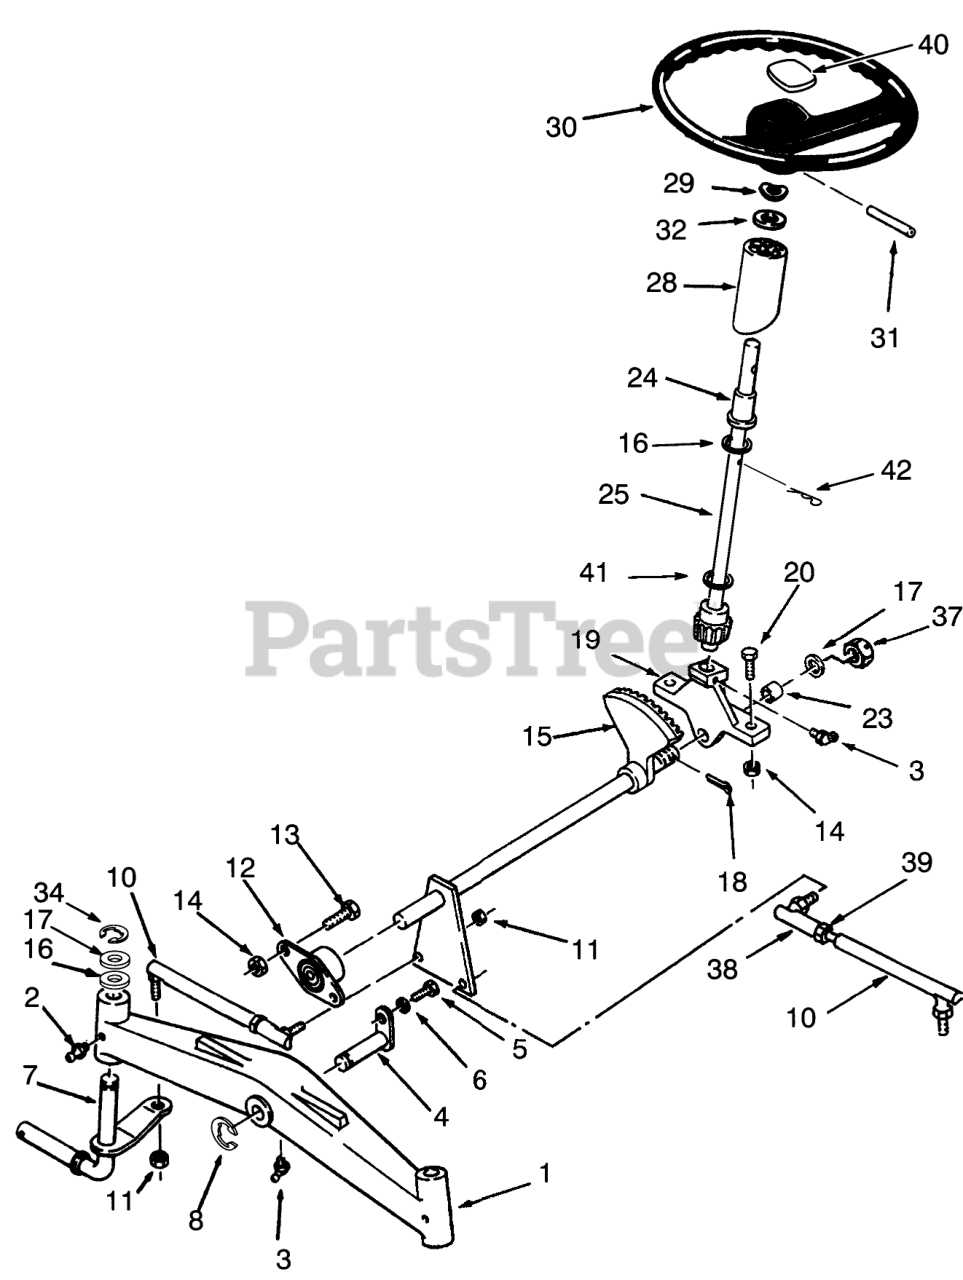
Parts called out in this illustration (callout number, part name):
1	AXLE-FRONT
2	FITTING-GREASE
3	FITTING-GREASE
4	PIN AND PLATE ASM
5	SCREW-HH
6	WASHER-LOCK
7	RH SPINDLE WA
8	E-RING
10	Tie Rod Assembly (Incl. Ref. #38 & 39)
11	NUT HEX 3/8-24 E.S.
12	BEARING-FLANGED
13	SCREW-HH
14	NUT-LOCK, NI
15	Shaft
16	WASHER-SHIM
17	WASHER
18	PIN-COTTER
19	Support-Steering
20	SCREW-HH
23	BEARING-BRONZE
24	BEARING-FLANGED
25	STEERING SHAFT ASM
28	TUBE-STEERING
29	WASHER-BOWED
30	Steering Wheel (Incl. Ref. #40)
31	PIN-ROLL
32	WASHER-FLAT
34	RING-RETAINING
37	NUT-HEX, SLOTTED
38	BALL-JOINT
40	STRG-WHL INSERT TORO
41	O-RING
42	PIN-COTTER
